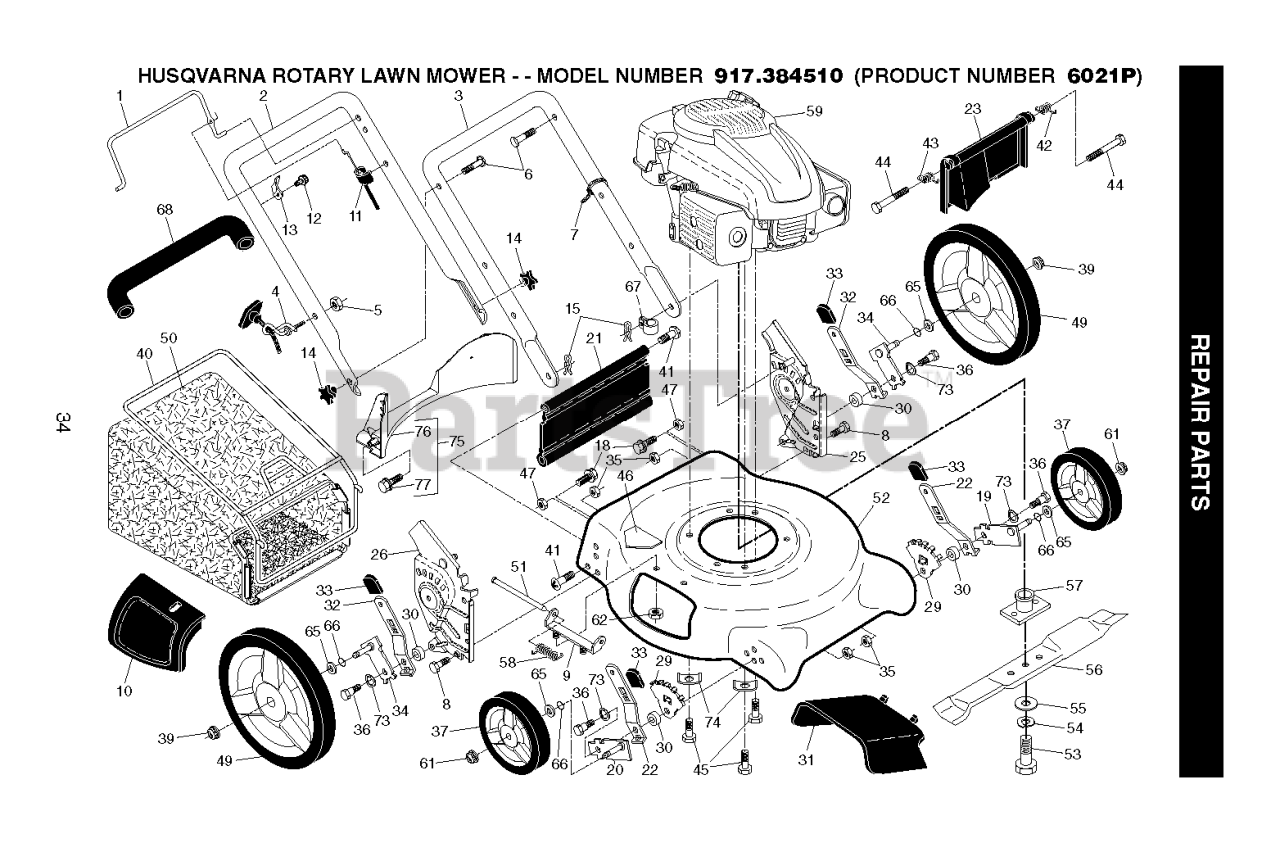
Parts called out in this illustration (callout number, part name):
1	BAIL.MZR.STD.ORANGE
2	UPPERHANDLE(INCLUDES FOAMGRIP)
3	HANDLE.LOWER.GREY
4	RB GUIDE.ROPE.STD.BLK.ZIN WSL
5	NUT
6	BOLT, HANDLE 5/16-18X1.75
7	TIE GUIDE
8	BOLT.FIN.HEX.5/16-18X3/4
9	BRACKET.ASM.HOUSING.EZ.MUL
10	RP DOOR.MULCH.21".REAR.PUSH.GR
11	CABLE.ENGINE.ZONE.CONTROL
13	BRACKET.UPSTOP.RT
14	KNOB.HANDLE.PLASTIC.STAR.BLACK
15	HAIRPIN COTTER
18	SCREW 1/4X20
19	AXLE ARM ASSY FRONT LH
20	AXLE ARM ASSY FRONT RH
21	RP_KIT.SKIRT.21 DOMED.W/LIP
22	SELECTOR SPRING, FRONT
23	REAR DOOR ASSY
25	RP BRKT.ASM.HAND.HW.21.LT.ORNG
26	RP BRKT.ASM.HAND.HW.21RT.ORNG
29	WHEEL ADJ BRACKET FRONT
30	SPACER.HEIGHT.ADJUSTER
31	DEFLECTOR.CLIPPING.21.GREY
32	SPRING.SEL.EXT.21.DOMED.12/14
34	AXLE ARM ASSY REAR LH
35	NUT.FLANGE.HEX.5/16X18.BLACK
36	SHOULDER BOLT 5/16-18
37	WHEEL & TIRES ASSY, FRONT
39	NUT.HEX.FLANGE.3/8-16.LOCKNUT
40	FRAME.BAG.21.REAR.DOMED.PUSH
41	HINGE SCREW
42	SPRING.LH.22.REAR.DOOR.EZ.EMPT
43	SPRING.RH.22.REAR.DOOR.EZ.
45	BOLT 3/8-16X1-1/8
46	DANGER DECAL
47	NUT.LOCK.5/16-18
48	AXLE ARM ASSY REAR RH
49	WHEEL ASSY
50	GBAG.2323247.SILVER
51	ROD.HINGE.COMBI-C
52	RP KIT.HSG.
53	SCREW, HEX HD 3/8-24 X 1-3/8
54	LOCKWASHER
55	WASHER,HARDEN
56	BLADE.21.PUSH/RWGD/FWGD
57	RP BLADE ADAPTER
58	TORSION SPRING
61	NUT.HEX.FLANGE.3/8-16.LO(3 2)
62	LOCKNUT.NYLOC.1/4-20
65	WASHER PM
66	O-RING..070X.487.NEOPRENE
67	CLIP.CABLE.BLK
68	GRIP.HANDLE.FOAM
73	WASHER.CURVED.CYLINDRICAL
74	WASHER.ENGINE.BZP
75	KIT.BAFFLE.REAR.PLASTIC.21.RD
76	BAFFLE.REAR.PLASTIC.21.RD.ECON
77	SCREW.HX.13X.750
